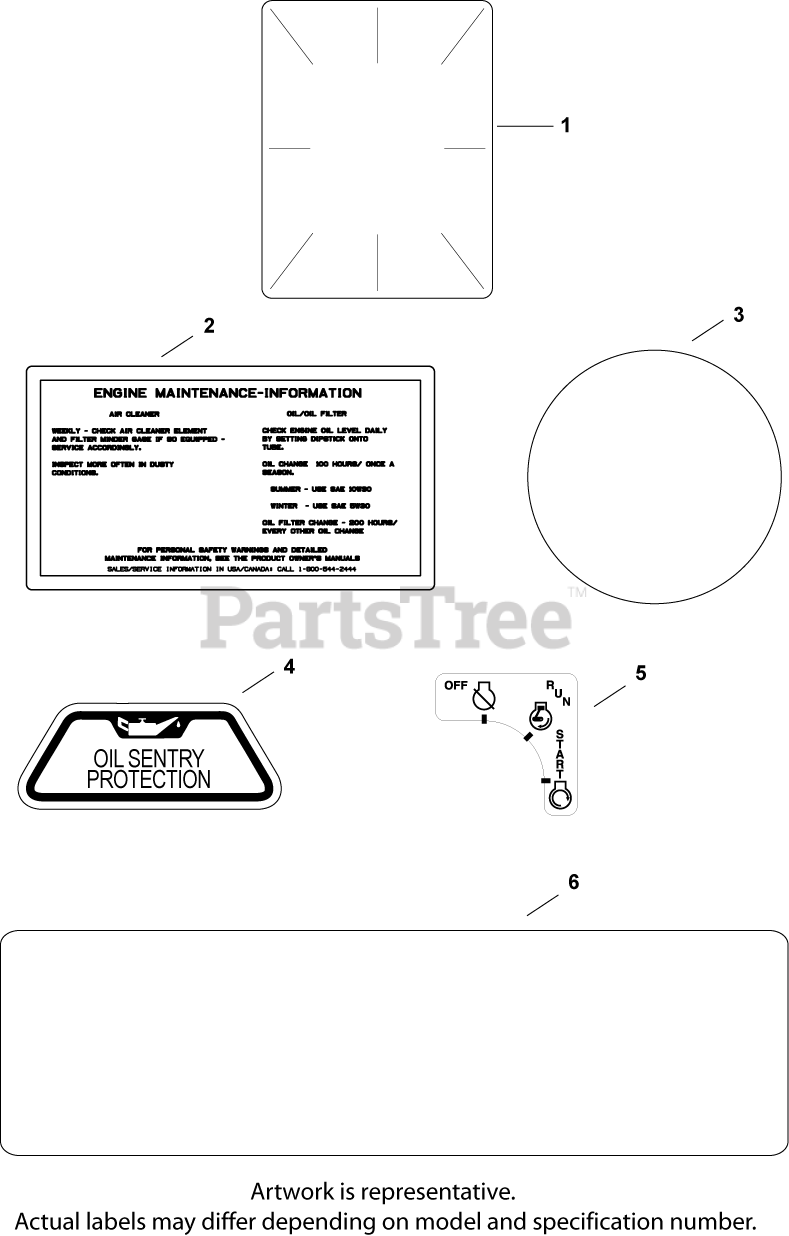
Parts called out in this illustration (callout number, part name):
1	DECAL, CLEAR LAMINATE USE 25 113 70-S
2	DECAL, AIR CLEANER - (#DSC)
3	DECAL, GRASS SCREEN USE 24 113 499-S
4	DECAL, OIL SENTRY - (#DSC)
5	DECAL, KEY SWITCH
6	DECAL, 20 HP - DISCONTINUED
